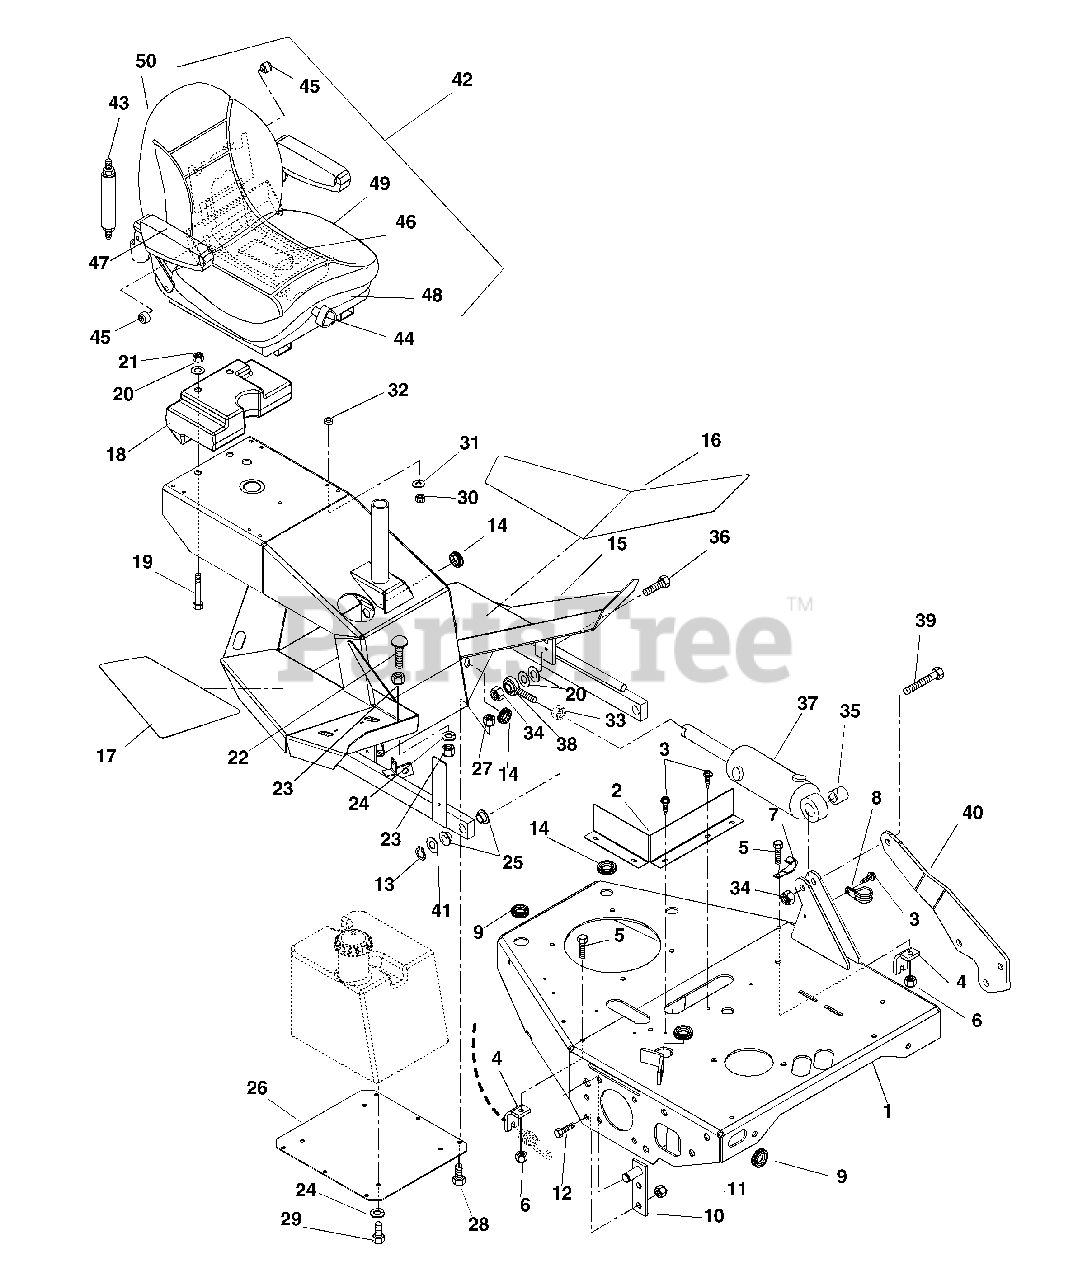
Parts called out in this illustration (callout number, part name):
1	Weldment, Frame
2	Heat Shield
3	Screw-Tapping .25-20 x .50 Hex Washer Head
4	Bracket,Cable
5	Bolt-Hex .31-18 x 1.00 Grade 5
6	Nut-Locking-Nylon .31-18
7	J-Clamp
8	Clamp, Steel 1.0
9	Grommet 1.25
10	Weldment, Pivot
11	Nut-Locking-Nylon .50-13
12	Bolt-Hex .50-13 x 1.50 Grade 5
13	Ring-Retaining-External .689 x .077
14	Grommet 75 x 1.06 x 1.38
15	Weldment, Sulky
16	Pad, Left Hand Floorboard
17	Pad, Right Hand Floorboard
18	Weight, Rear
19	Bolt-Hex .50-13 x 4.00 Grade 5
20	Washer-Flat-Steel .531 x 1.06 x .095
21	Nut-Locking-Nylon .50-13
22	Bolt-Round Head Square Neck .31-18 x 1.50 Grade 5
23	Nut-Hex .31-18
24	Washer-Locking .31 x .078
25	Bushing, Flange-Nylon .762 x 1.00 x .58 x 1.48
26	Plate, Bottom
27	Nut-Locking-Nylon .38-16
28	Bolt-Hex .38-16 x 1.00 Grade 5
29	Bolt-Hex .31-18 x .75 Grade 5
30	Nut-Locking-Nylon M8-1.25
31	Washer-Flat-Steel .38 x .875 x .083
32	Bushing-Sleeve .377 x .624 x .235
33	Nut-Jam .50-20 Grade 2
34	Nut-Locking-Nylon .50-13
35	Bushing, .516 x 1.00 x 1.05
36	Bolt-Hex .50-13 X 2.25 Grade 5
37	Cylinder, Platform Lift
38	Assembly-Rod End Right Hand
39	Bolt-Hex .50-13 x 3.00 Grade 5
40	Support, Cylinder Brace
41	Washer-Hardened-Thrust .758 x 1.23 x .031
42	Seat-Suspension
43	Kit-Damper with Hardware
44	Kit-Knob (1 per bag)
45	Kit-Roller (4 per bag)
46	Kit-Spring Cable (1 per bag)
47	Kit-Arm Pad (1 per bag)
48	Kit-Adjuster (1 per carton)
49	Kit-Cushion (1 per carton)
50	Kit-Seatback
